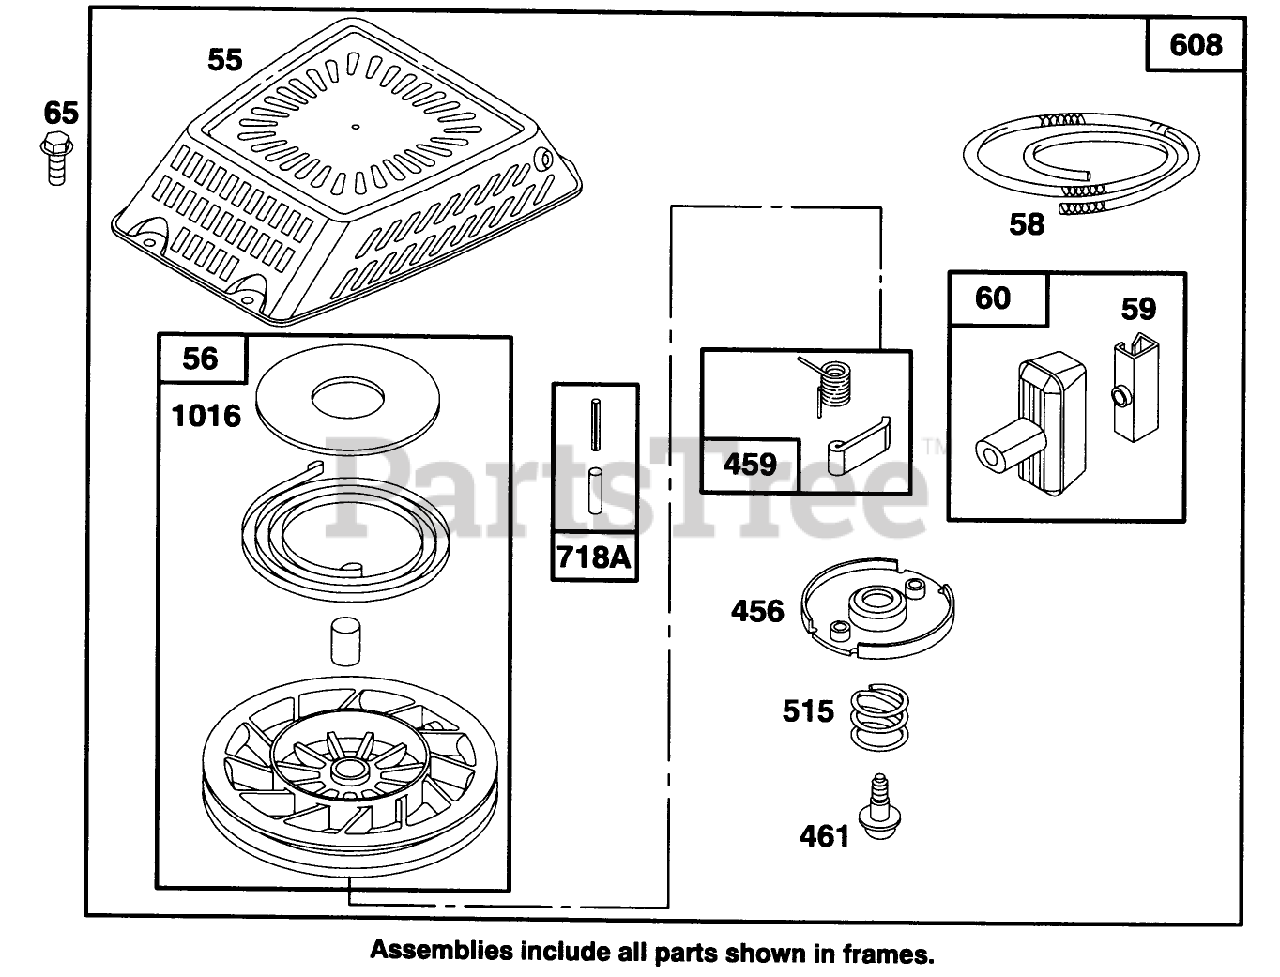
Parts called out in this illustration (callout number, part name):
58	Rope-Starter (Cut To Suit)
60	HANDLE-REWIND STARTER
456	RETAINER - SPRING
515	SPRING - RETAINER
